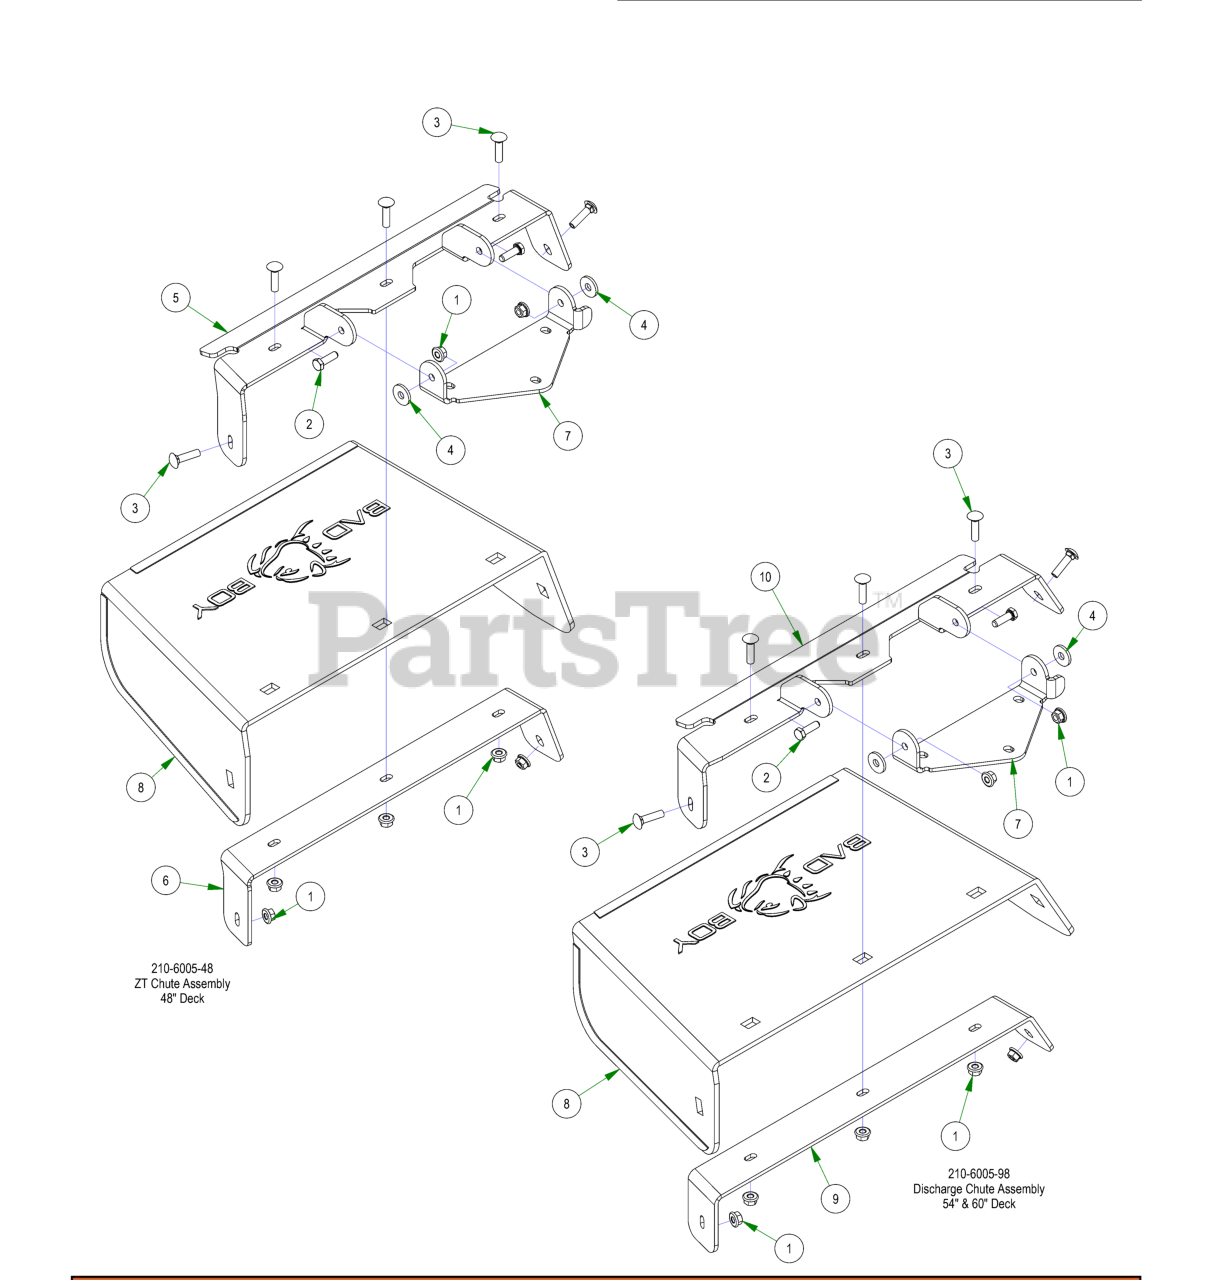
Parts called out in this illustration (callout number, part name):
1	5/16-18 NYLON INSERT FLANGE LOCKNUT ZINC
2	5/16-18 X 1 HEX CAP SCREW (GR.5) ZINC
3	5/16-18 X 1-1/4 CARRIAGE BOLT ZINC
4	.360 ID X .983 OD X .120 THICK FLAT WASHER NYLON
5	Discharge Upper Chute Bracket
6	Discharge Lower Chute Bracket
7	Discharge Chute Hanger (deck mounted)
8	Rubber Discharge Chute
9	60" Discharge Lower Bracket
10	60" Discharge Chute Upper Hanger
